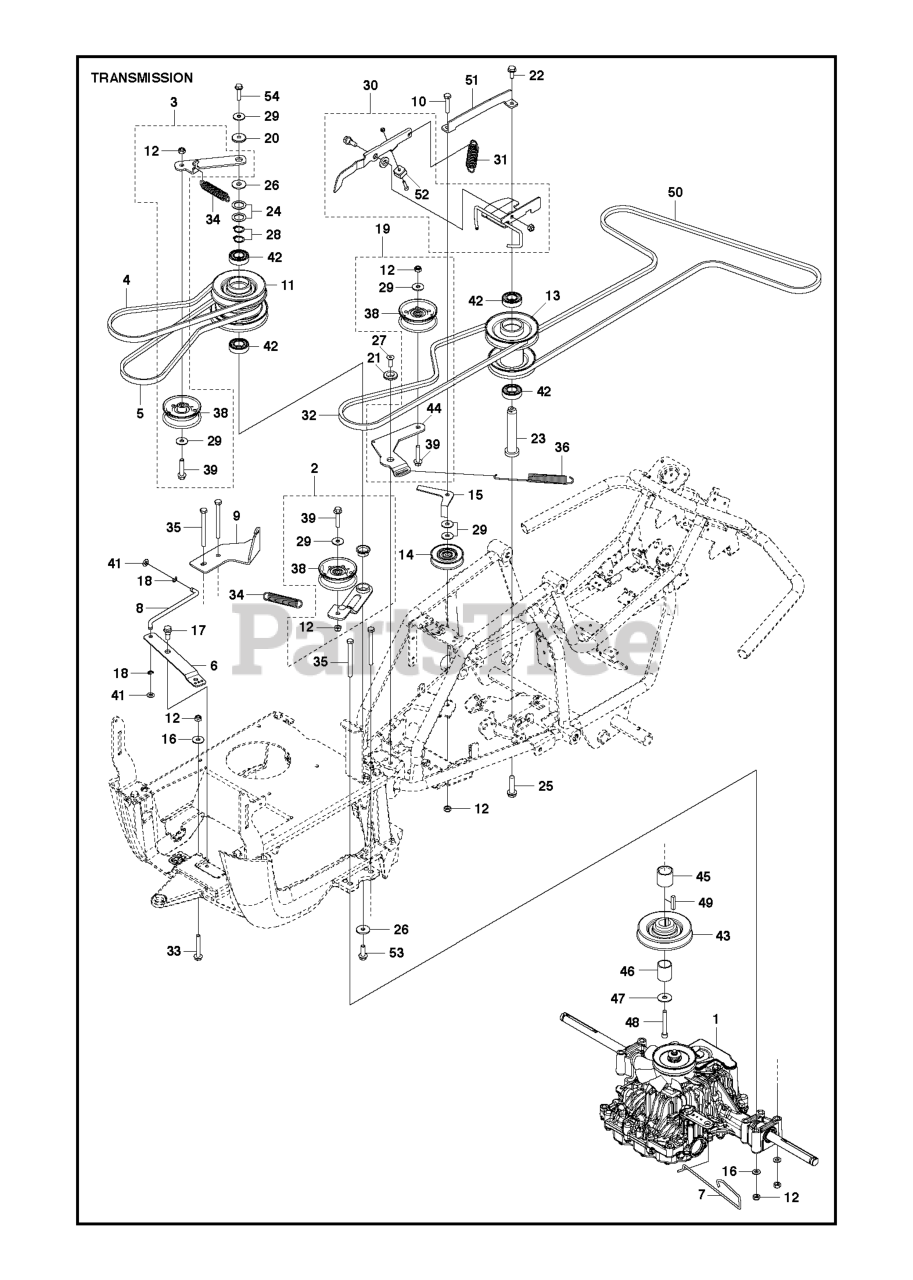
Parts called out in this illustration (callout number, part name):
1	TRANSMISSION
2	BELT TENSIONER ASSY
3	BELT TENSIONER ASSY
12	LOCKNUT M8
16	WASHER BRB 8.4X17
19	BELT TENSIONER
20	WASHER
28	RETAINING RING SGA 20
30	BRAKE ASSY
32	BELT INTERMEDIATE 42 SD
33	SCREW EHHFM
38	IDLER PULLEY
42	BALL BEARING 6004-2RS1
44	BELT TENSIONER
45	SPACING SLEEVE
50	BELT DRIVE 42 SD
54	SCREW EHHFM
